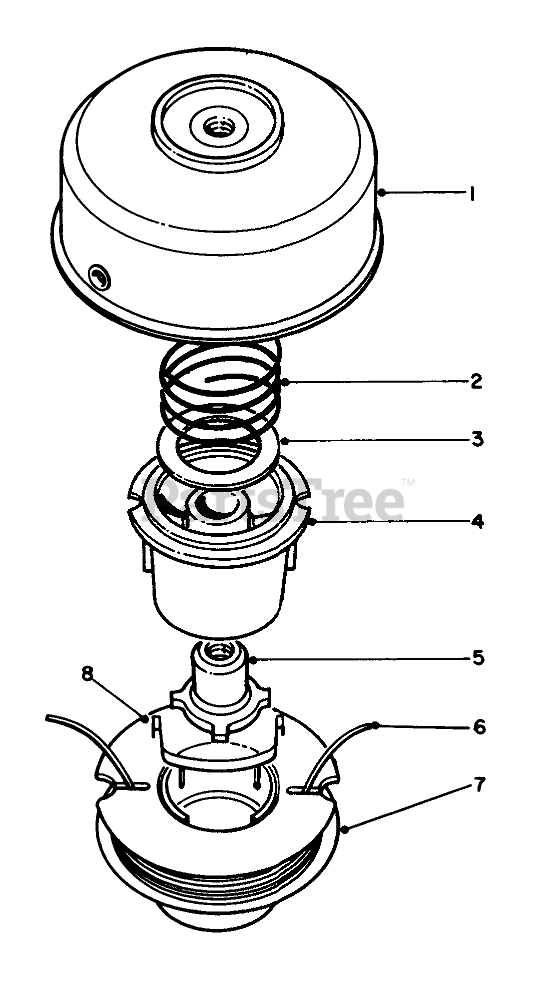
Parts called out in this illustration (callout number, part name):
1	ASM - TRIMMER DRUM & EYELET
2	SPRING
3	WASHER-FLAT
4	SPOOL CORE
5	LH DRIVER
6	REPL LINE PKG
7	Spool Housing
8	SADDLE-SPOOL CAP
